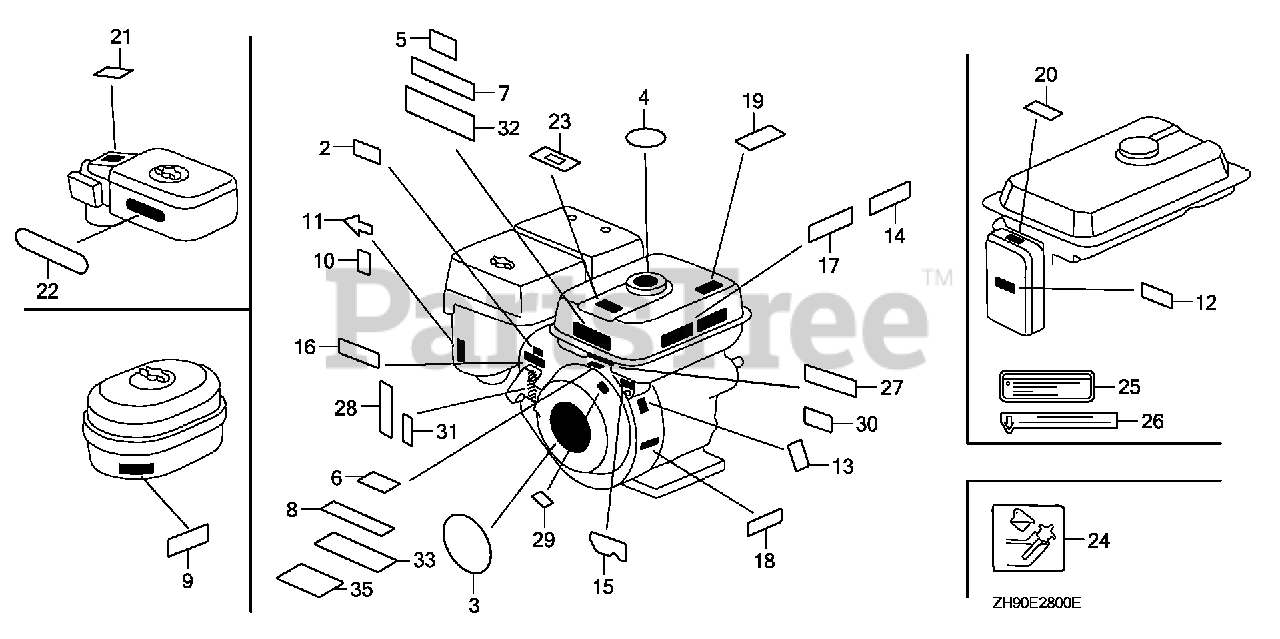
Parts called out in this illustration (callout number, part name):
3	EMBLEM (GX270 9.0)
7	LABEL, CAUTION (ENGLISH, ETC.)
10	MARK, CHOKE (ORANGE)
17	MARK, OIL ALERT (ENGLISH)
